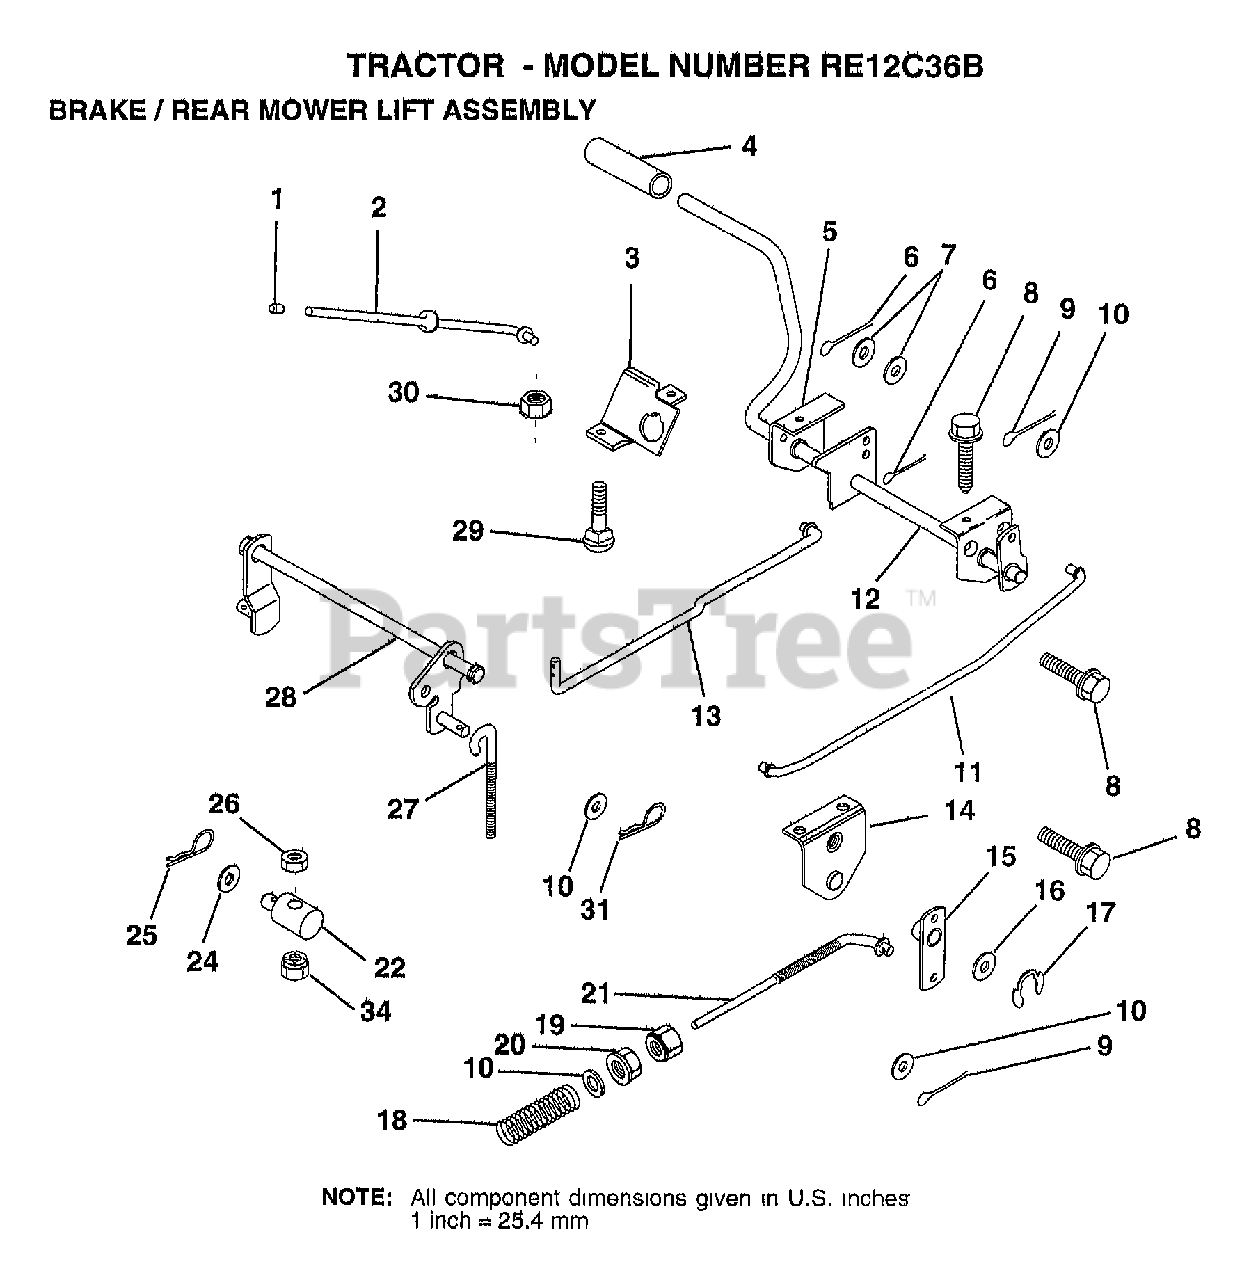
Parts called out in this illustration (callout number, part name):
1	PLUNGER CAP T
2	"ROD,PARK BRAKE"
3	"BRKT,PARK BRAKE"
4	FOOT PEDAL COVER
5	"BRKT,CLU PEDAL LH"
7	WASHER
8	SCREW LT
9	COTTER PIN
10	WASHER
11	"ROD,FRT BRAKE"
12	PEDAL ASM CL/BK36
13	"ROD,CLUTCH"
14	"BRKT,LIFT SHAFT"
15	PVT BRAKE ARM ASM
16	WASHER T
17	KLIP RING
18	SPRING ROD BRAKE
19	NUT
20	NUT
22	TRUNNION.LIFT.
24	WASHER
25	SPRING.RETAINER
26	LOCKNUT
27	"LINK, MOWER REAR"
28	LIFT ASM MOW REAR
31	RETAINER.SPRING
